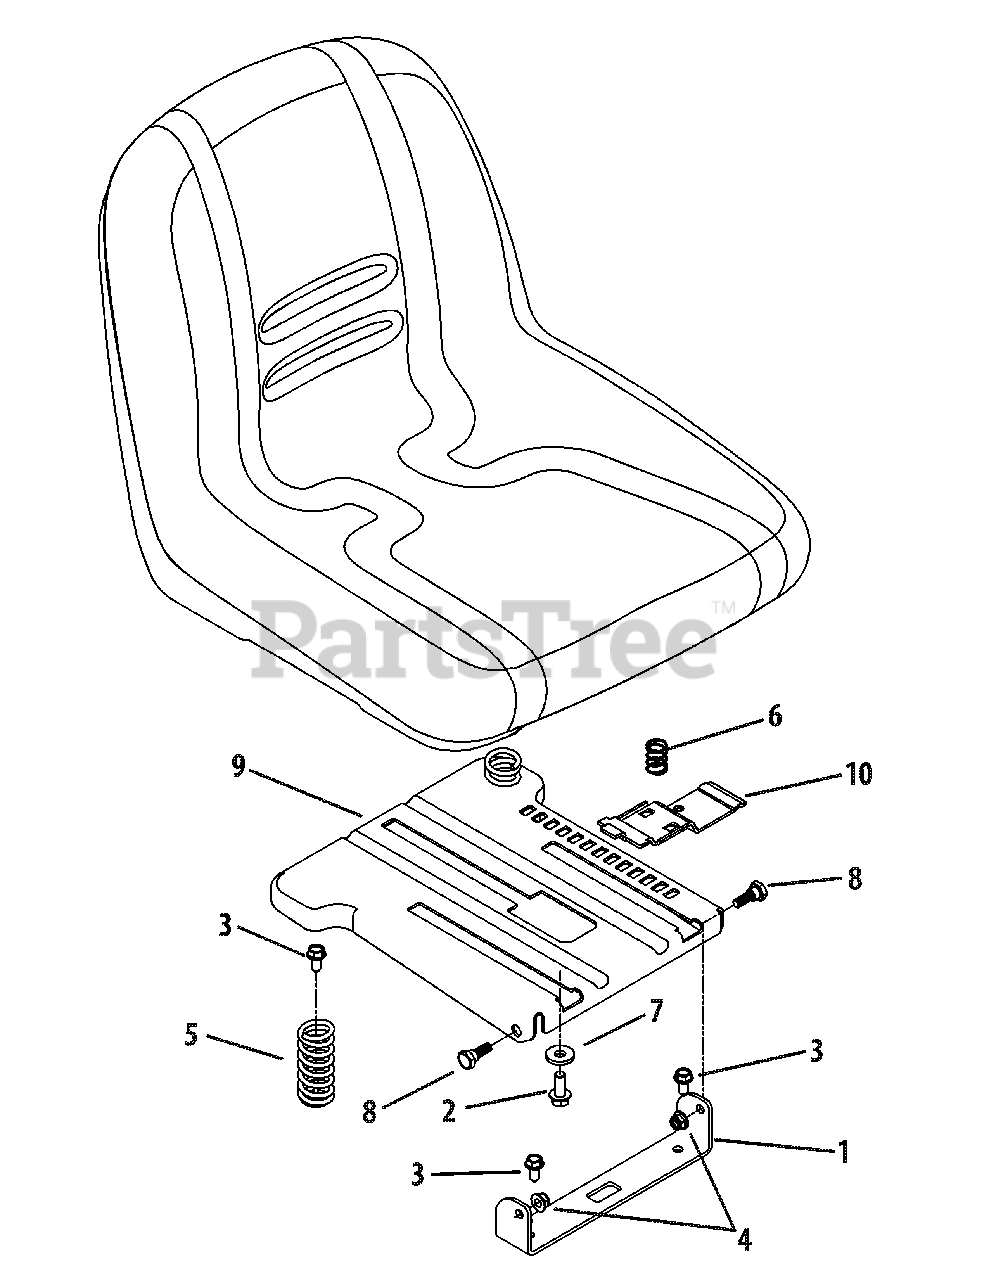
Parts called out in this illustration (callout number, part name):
1	Seat Bracket - Black Jack
1	Seat Bracket - Green
2	Hex Flange Bolt, 3/8-16 x .875
3	Hex Washer Screw, 5/16-18 x .750
4	Flange Lock Nut, 5/16-18
5	Compression Spring
6	Compression Spring
7	Flat Washer, .385 x 1.0 x .135
8	Shoulder Screw, .437 x .268 x 5/16-18
9	Seat Mount Bracket - Black Jack
9	Seat Mount Bracket - Green
10	Seat Adjustment Lever
